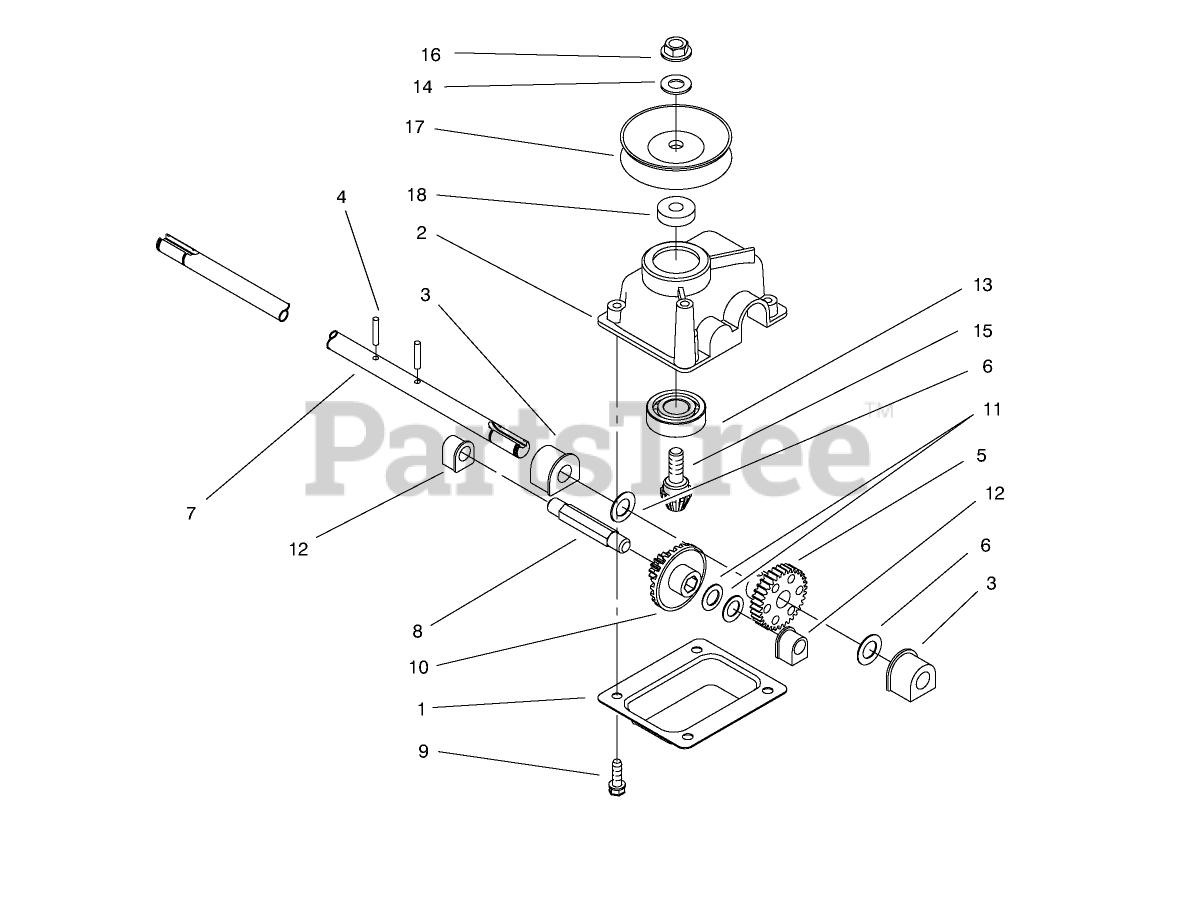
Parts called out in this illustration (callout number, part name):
3	BUSHING
4	PIN-GROOVE
6	WASHER-PLAIN
8	SHAFT-INTERMEDIATE
9	SCREW-HWH
11	WASHER-THRUST
12	BUSHING
13	BEARING-BALL
14	WASHER-FLAT
16	NUT-HEX
17	HALF-PULLEY
18	SPACER
